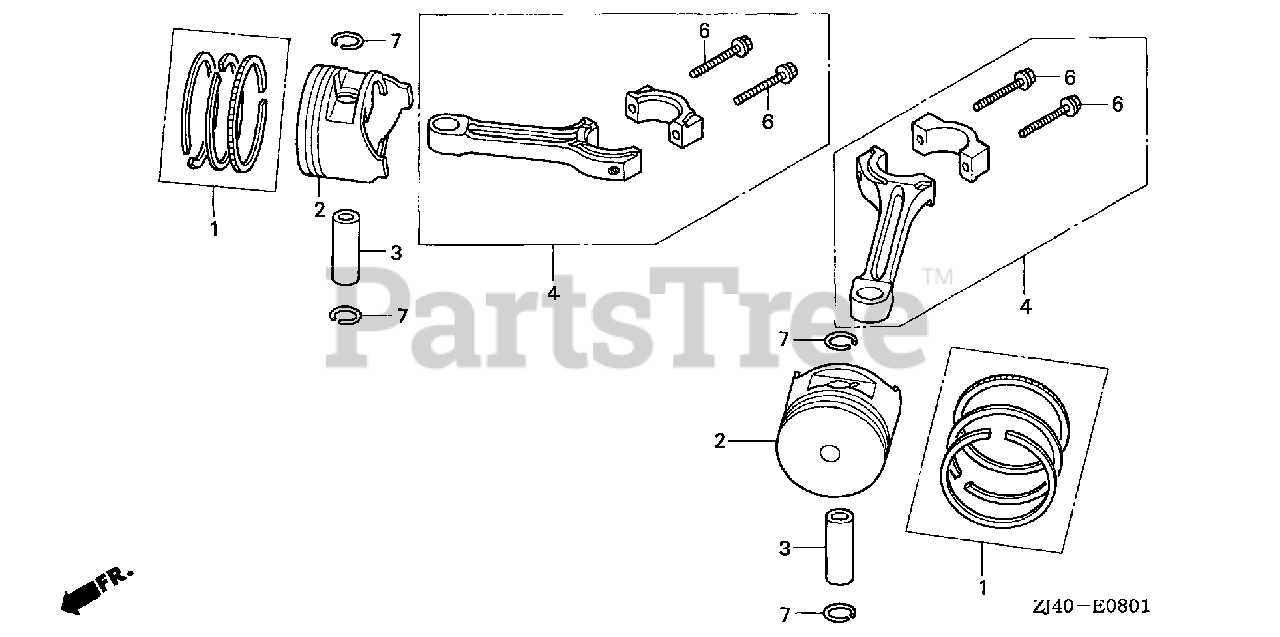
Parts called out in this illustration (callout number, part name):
1	RING SET, PISTON (STD) (NIPPON)
1	RING SET, PISTON (0.25)
1	RING SET, PISTON (0.50)
1	RING SET, PISTON (0.75)
2	PISTON (STD)
2	PISTON (0.25)
2	PISTON (0.50)
2	PISTON (0.75)
3	PIN, PISTON
4	ROD ASSY., CONNECTING
6	BOLT, CONNECTING ROD (6X37)
7	CLIP, PISTON PIN (18MM)
